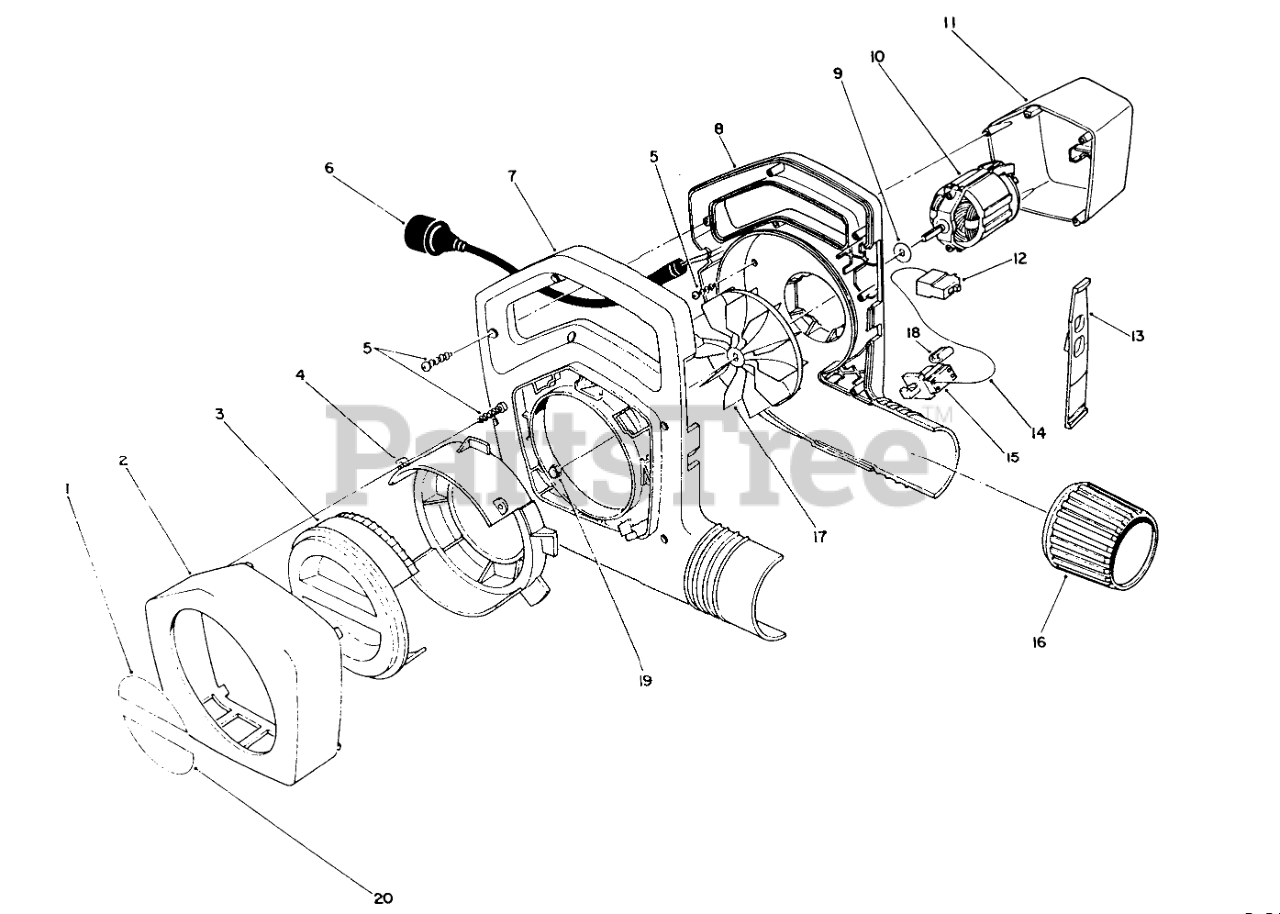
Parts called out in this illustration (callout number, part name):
1	UPPER CHOKE DECAL-CLUB
2	Ring-Trim
3	Adjuster-Choke
4	Ring-Tab
5	Screw
6	Cord-Power Supply
7	BLOWER HOUSING, RH
8	Housing-L.H.
9	Washer-Impeller
10	MOTOR, BLOWER (450/550)
11	Cover-Motor
12	Switch-On/Off
13	Cam-Switch-On/Off
14	WIRE -INTERNAL
15	SWITCH-INTERLOCK
16	Collar-Output
17	IMPELLER-NEW STYLE
18	NEW STYLE DUST PLUG
19	NUT-LOCK, CAP
20	LOWER CHOKE DECAL-CLUB
